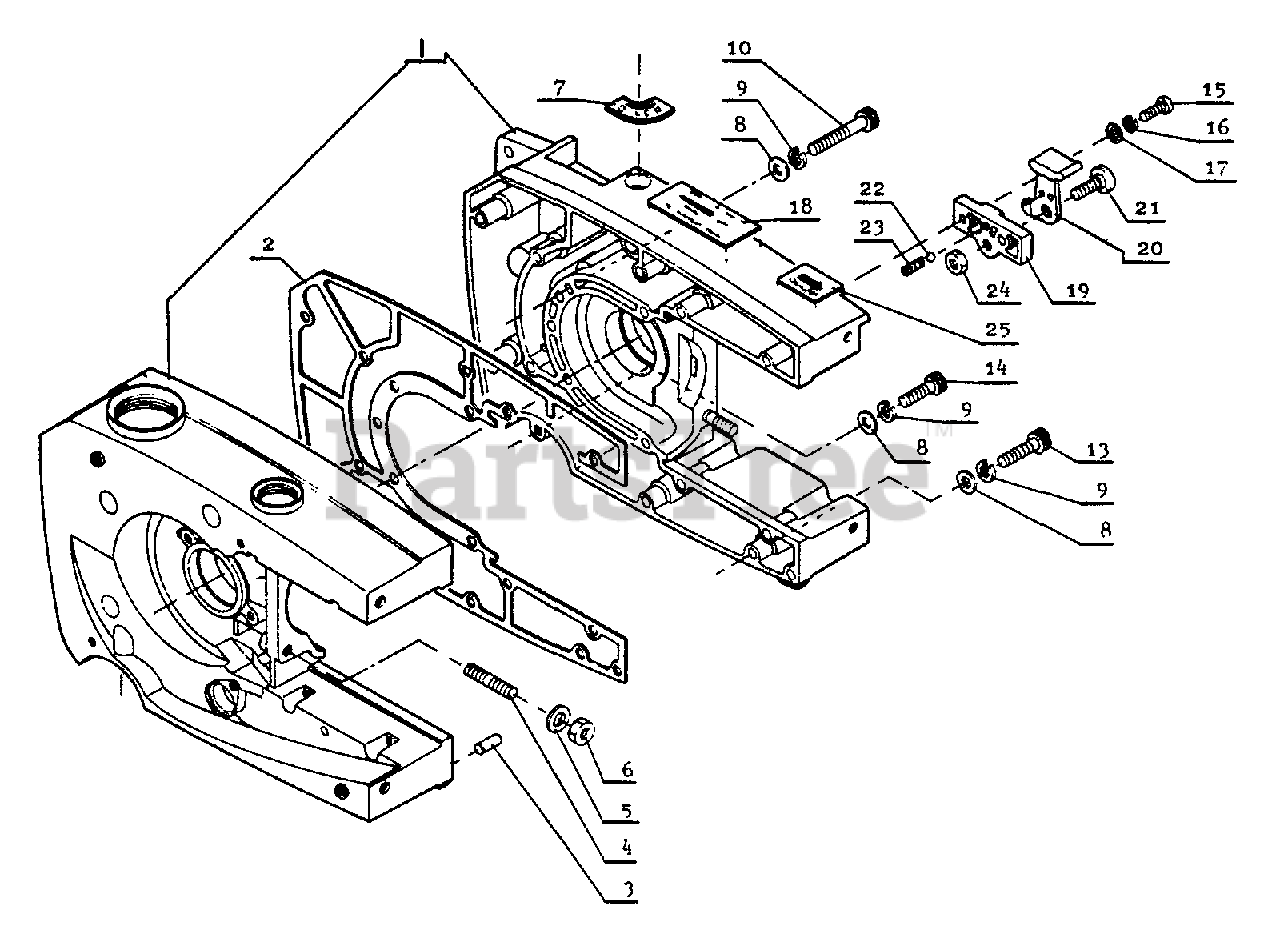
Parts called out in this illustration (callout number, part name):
1	CRANKCASE KIT
2	GASKET, CRANKCASE
3	PIN - LOCATING
5	WASHER - 6
6	LOCKNUT - 6
7	LABEL - OIL
8	WASHER - 5
9	LOCKWASHER - 5
10	SCREW - 5X35
13	SCREW - 5X30
14	SCREW - 5X18
15	SCREW - 4X10
16	LOCKWASHER - 4
17	WASHER - 4
18	LABEL - CAUTION
19	BRACKET
20	LEVER, DECOMPRESSION
21	SCREW - SET
22	VALVE, BALL
25	LABEL - DECOMPRESSION
